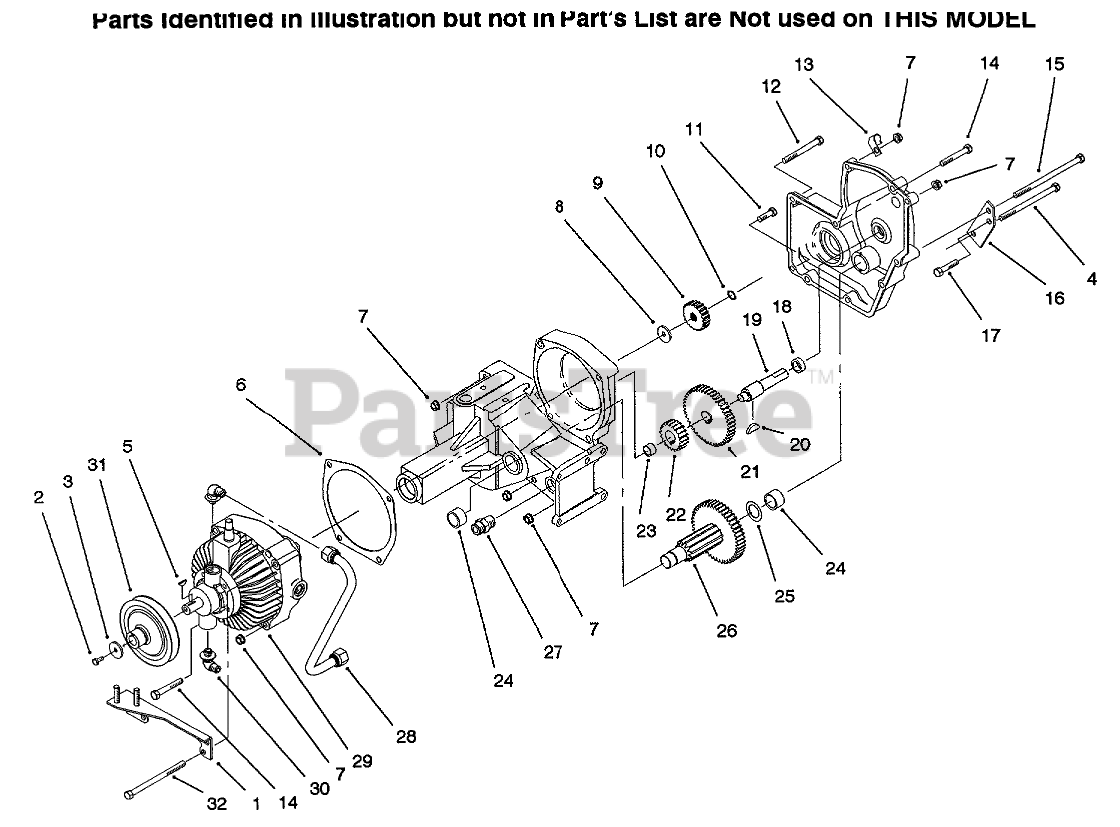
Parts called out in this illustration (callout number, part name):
1	ASSY-PLATE B
1:1	Plate
1:2	NON SERVICE PART
2	SCREW-HEX HD CAP
3	WASHER
4	SCREW-HH
5	KEY-WOODRUFF
6	GASKET
7	NUT-LOCK, NI
8	SPACER GEAR
9	GEAR 20 TEETH DRIVE
10	RING-SNAP, EXTERNAL
12	SCREW-HH
13	CLIP
15	SCREW-HH
16	BRACKET-BRAKEB
18	Race Thrust
19	SHAFT GEAR
20	Key
21	GEAR 46 TEETH
22	GEAR 20 TEETH
23	BEARING-NEEDLE
24	BEARING-NEEDLE
25	WASHER-THRUST
26	ASSY GEAR
26:1	GEAR 46T
26:2	PINION SHAFT
27	FITTING-TUBE
27	AXLE-REAR RH
28	ASSY-TUBE SUCTION
29	TRANSMISSION-PUMP
30	ELBOW
31	PULLEY
